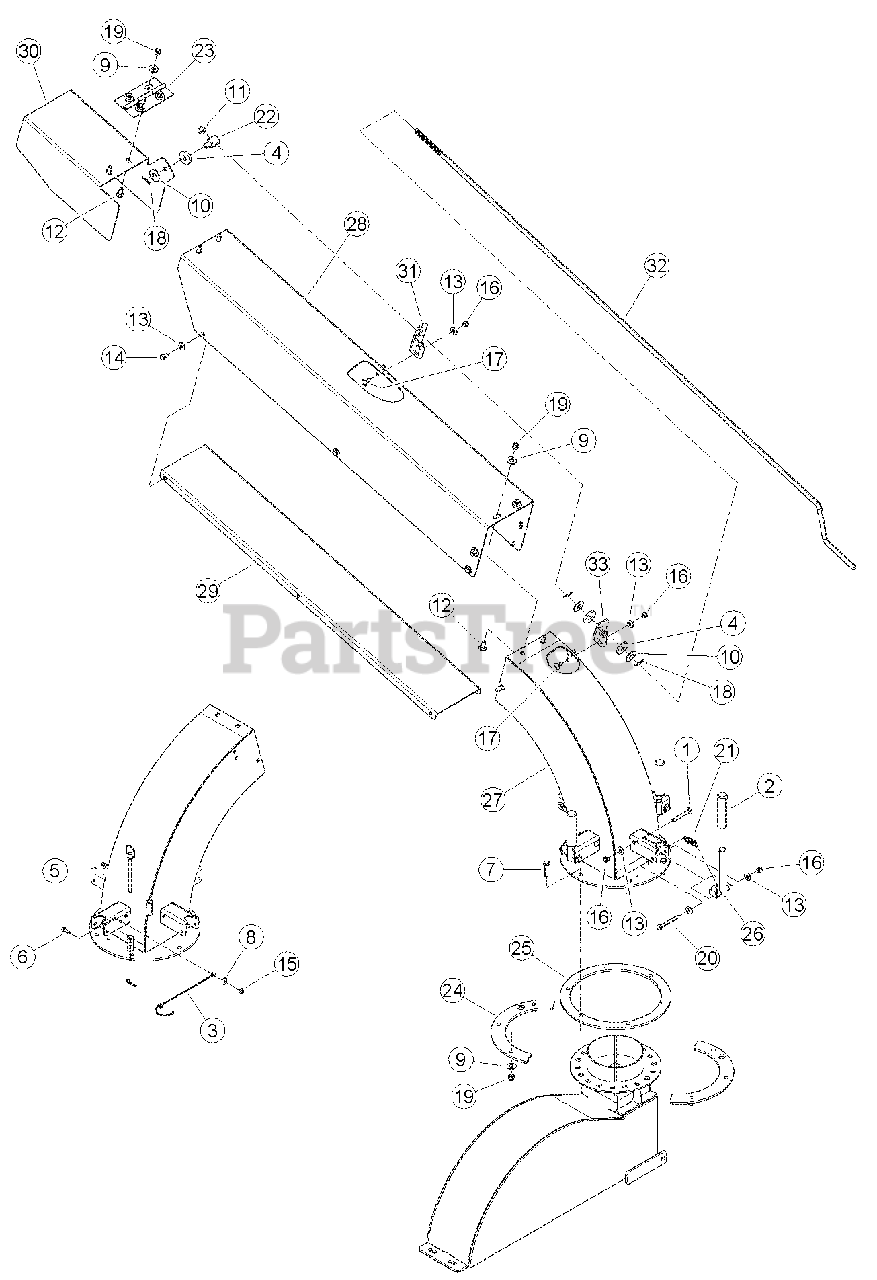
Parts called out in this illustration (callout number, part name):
1	BOLT, 5/16 X 2-1/2 CRG GR5 ZP
2	GRIP, TILT CONTROL
3	LANYARD, NYLON
4	WASHER, UHMW SPACER .515ID-1.50OD
5	PIN, 3/8 HITCH
6	BOLT, 1/4 X 3/4 HEX HD GR5 ZP
7	BOLT, 3/8 X 1-1/2 HEX HD GR5 ZP
8	WASHER, 1/4 FLAT ZP
9	WASHER, 3/8 FLAT ZP
10	WASHER, 1/2 FLAT ZP
11	NUT, 1/2 CENTERLOCK GRB ZP
12	BOLT, 3/8 X 1 CRG GR5 NC ZP
13	WASHER, 5/16 FLAT ZP
14	BOLT, 5/16 X 5/8 HEX HD GR5 ZP
15	NUT, 1/4 NE NYLOCK ZP
16	NUT, 5/16 NE NYLOCK ZP
17	BOLT, 5/16 X 3/4 CRG GR5 NC ZP
18	PIN, 1/8 X 1.00 COTTER ZP
19	NUT, 3/8 NE NYLOCK ZP
20	BOLT, 5/16 X 2-3/4 HEX HD GR5
21	SPRING, 1/2 X 2.00 LG ZP
22	PIVOT, HEIGHT ADJUSTMENT
23	HINGE, DISCHARGE CAP
24	RETAINER, DISCHARGE
25	SPACER, DISCHARGE CHUTE
26	WELDMENT, HANDLE
27	WELDMENT, DISCHARGE CHUTE
28	CHANNEL, DISCHARGE CHUTE
29	WELDMENT, DISCHARGE BOTTOM
30	CAP, DISCHARGE
31	STRIP, DISCHARGE
32	CRANK, DISCHARGE
33	BRACKET, DISCHARGE CRANK
